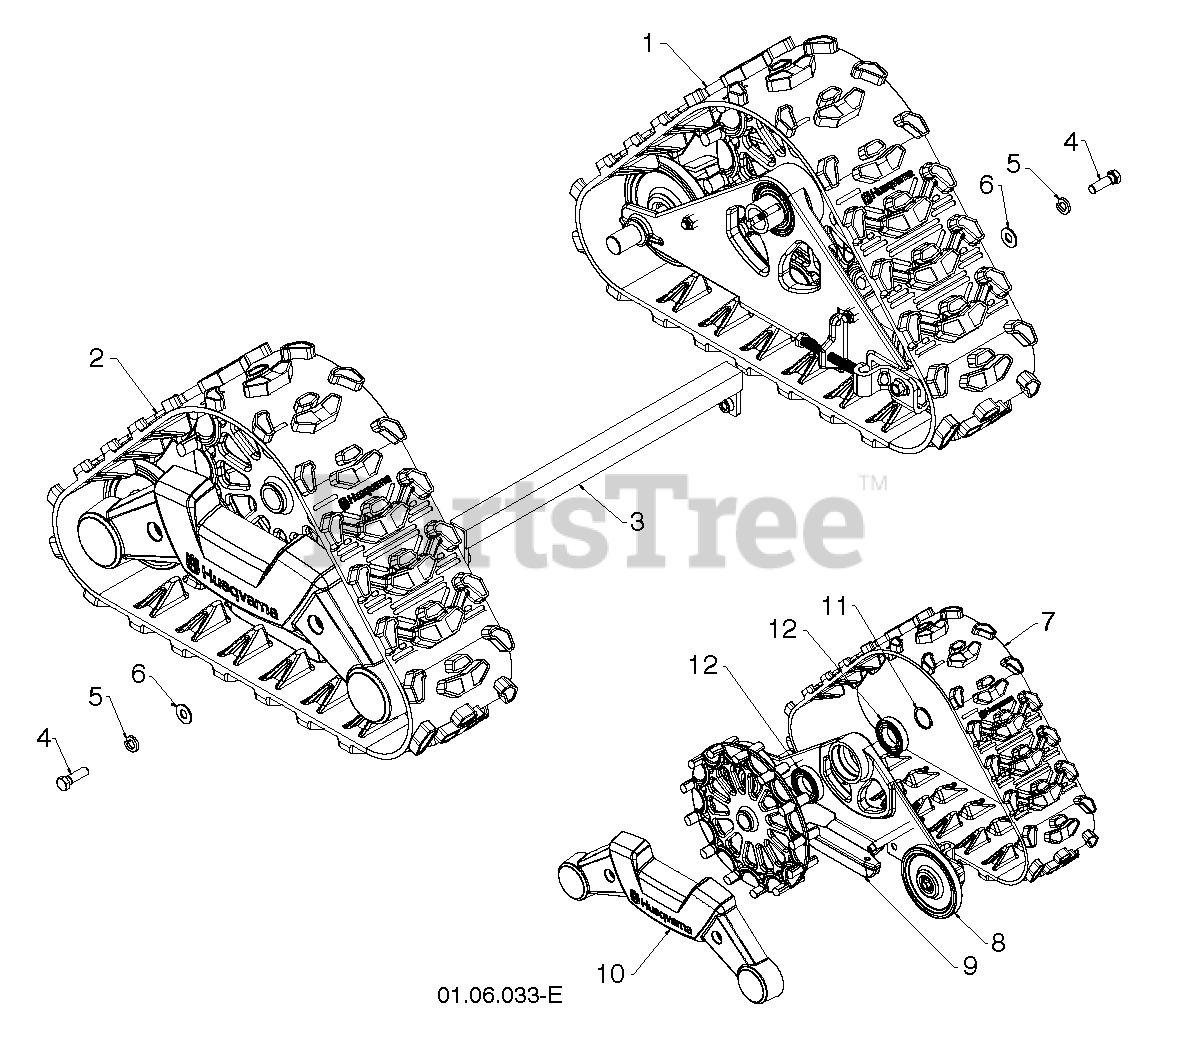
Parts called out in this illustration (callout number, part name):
1	WHEEL WHEEL TRACK ASSEMBLY LH
2	WHEEL WHEEL TRACK ASSEMBLY RH
3	SUPPORT.BRACE.ASM.TRACK.12
4	BOLT
5	LOCKWASHER
6	WASHER
7	RUBBER TRACK
8	WHEEL.IDLER.TRACK.SNOW
9	GUIDE TRACK
10	COVER TRACK
11	SNAP RING.1.25
12	BEARING.BALL.SHIELD.TRACK.SNOW
